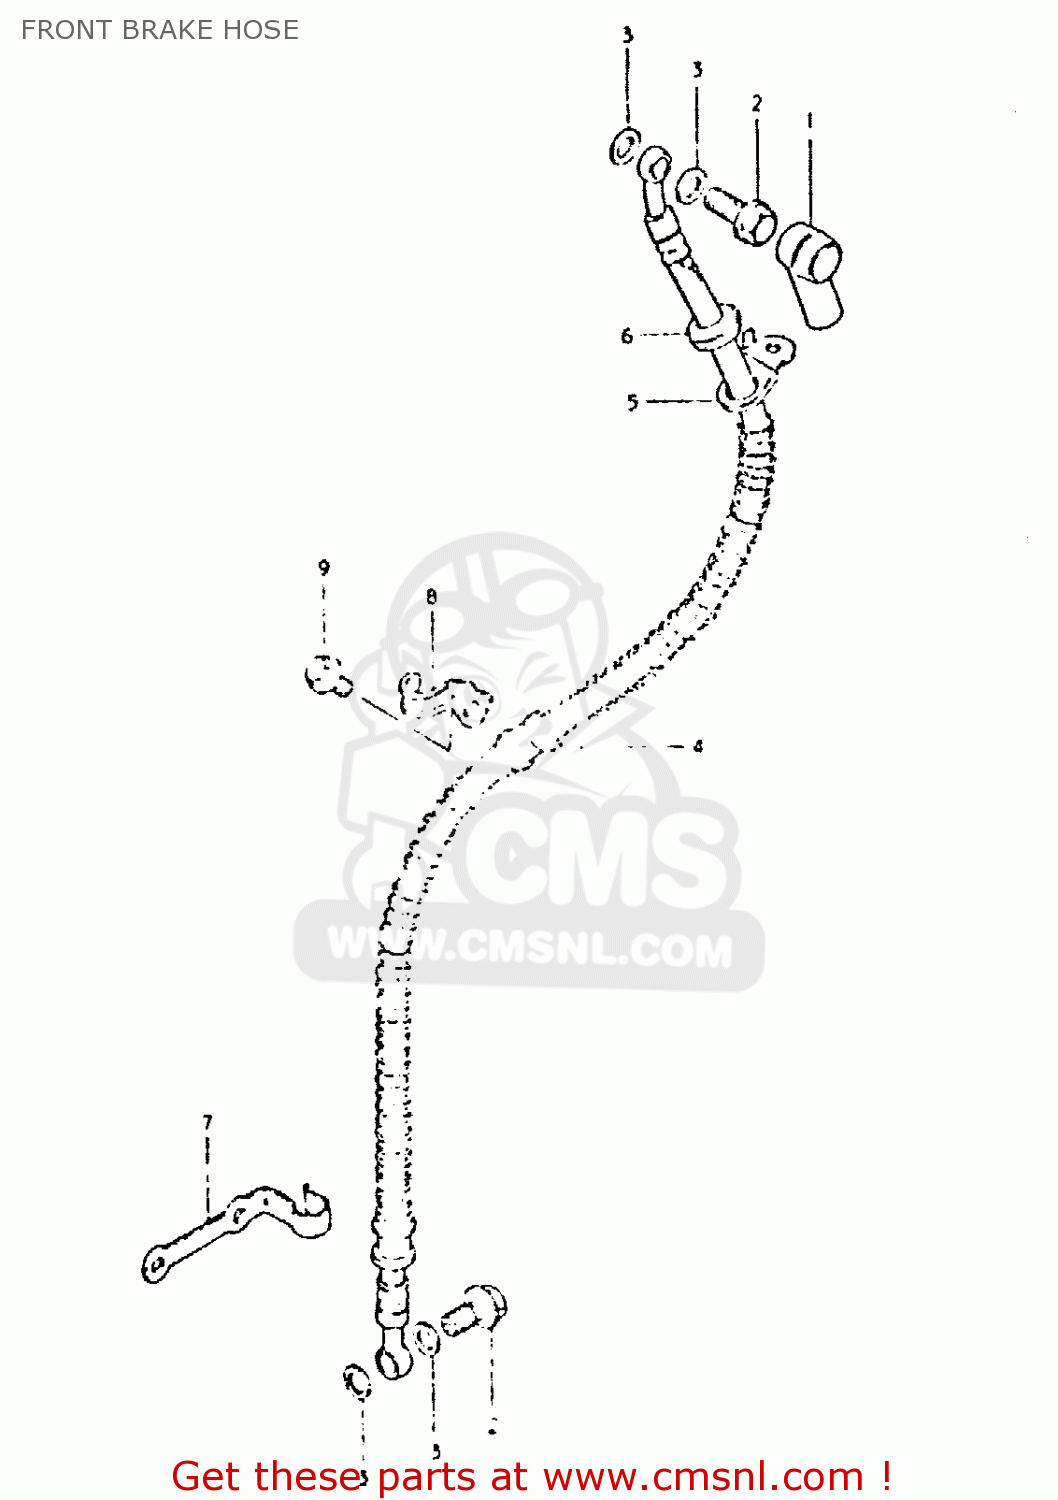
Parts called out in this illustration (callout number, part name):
1	BOOT,MASTER CYLINDER
2	BOLT,UNION
3	WASHER
4	HOSE,FRONT BRAKE
5	GUIDE,BRAKE HOSE
6	GROMMET
7	GUIDE,BRAKE HOSE NO.2
8	GUIDE,BRAKE HOSE NO.3
9	BOLT
